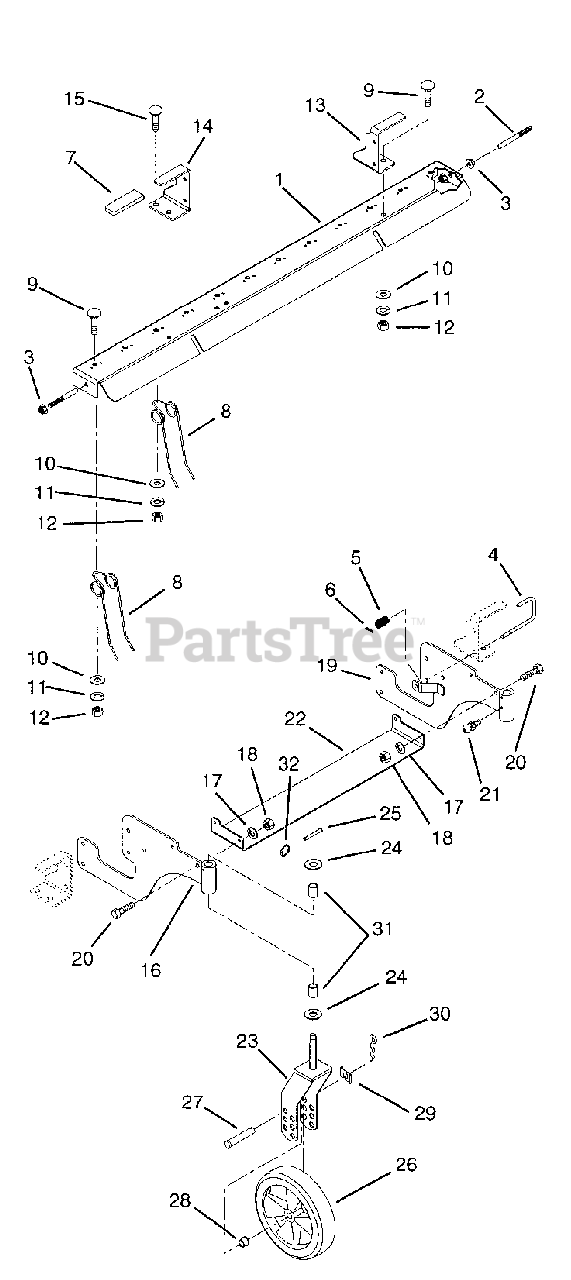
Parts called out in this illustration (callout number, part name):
1	Channel (73401700)
2	Rod (73401700)
3	Nut-Lkg-Flange .25-20
5	Spring .63 x .53
6	Roll Pin .094 x .750
7	Grip
8	Tine (73401700)
9	Bolt-Rnd Hd Sq Nk .31-18 x .75 (73401700)
10	Washer-Flat-Stl .328 x 1.0 x .094 (73401700)
11	Washer-Lck .312 x .097 (73401700)
12	Nut-Hex .31-18 (73401700)
13	Bracket-Channel Pvt L
14	Bracket-Channel Pvt R
15	Bolt-Rnd Hd Sq Nk .31-18 x 1.0
16	Support-Channel A
17	Washer-Lck .250 x .077
18	Nut-Hex .25-20
19	Support-Channel L
20	Bolt-Hex .25-20 x .75
21	Fitting-Lube .25-28 x .256
23	Wheel Yoke Weldment
24	Washer-Flat-St I .630 x 1.25
25	Pin-Clevis .25 x 1.75
26	Wheel .5 Bore 1.5 Hub
27	Clevis Pin
28	Bushing-Flange
29	Axle Tab
30	Pin-Hair Int .15 x .43 x 2.75
31	Bushing-Sleeve
32	Kickout Ring
